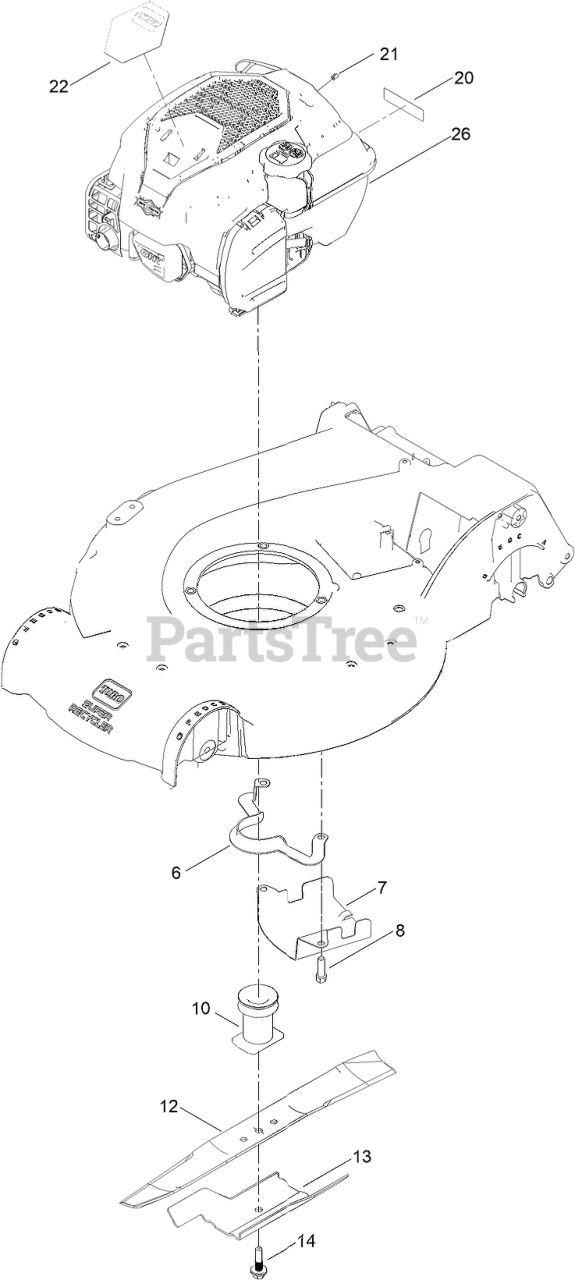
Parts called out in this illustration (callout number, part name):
6	GUIDE-BELT
7	SHIELD-GRASS
8	SCREW-TAPTITE
10	DRIVER-BLADE
12	BLADE-21IN, RECYCLING
13	ACCELERATOR-BLADE
14	BOLT-BLADE
20	DECAL-ARRESTOR, SPARK
21	STOP-ROPE
22	DECAL-ENGINE
